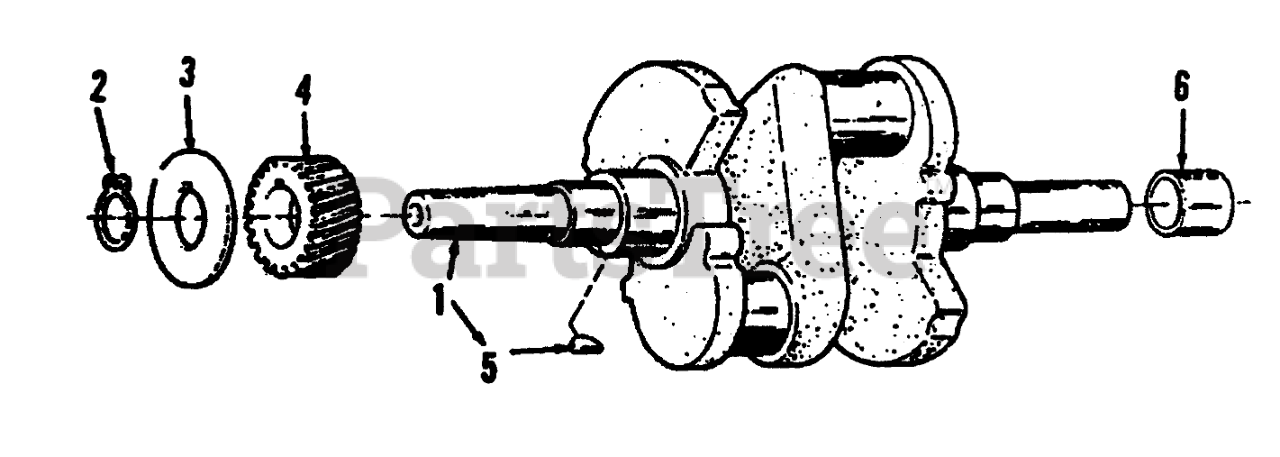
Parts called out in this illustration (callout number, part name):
1	CRANKSHAFT
2	Retaining Ring
3	Washer
4	Gear
5	Key
6	Cover-Valve
